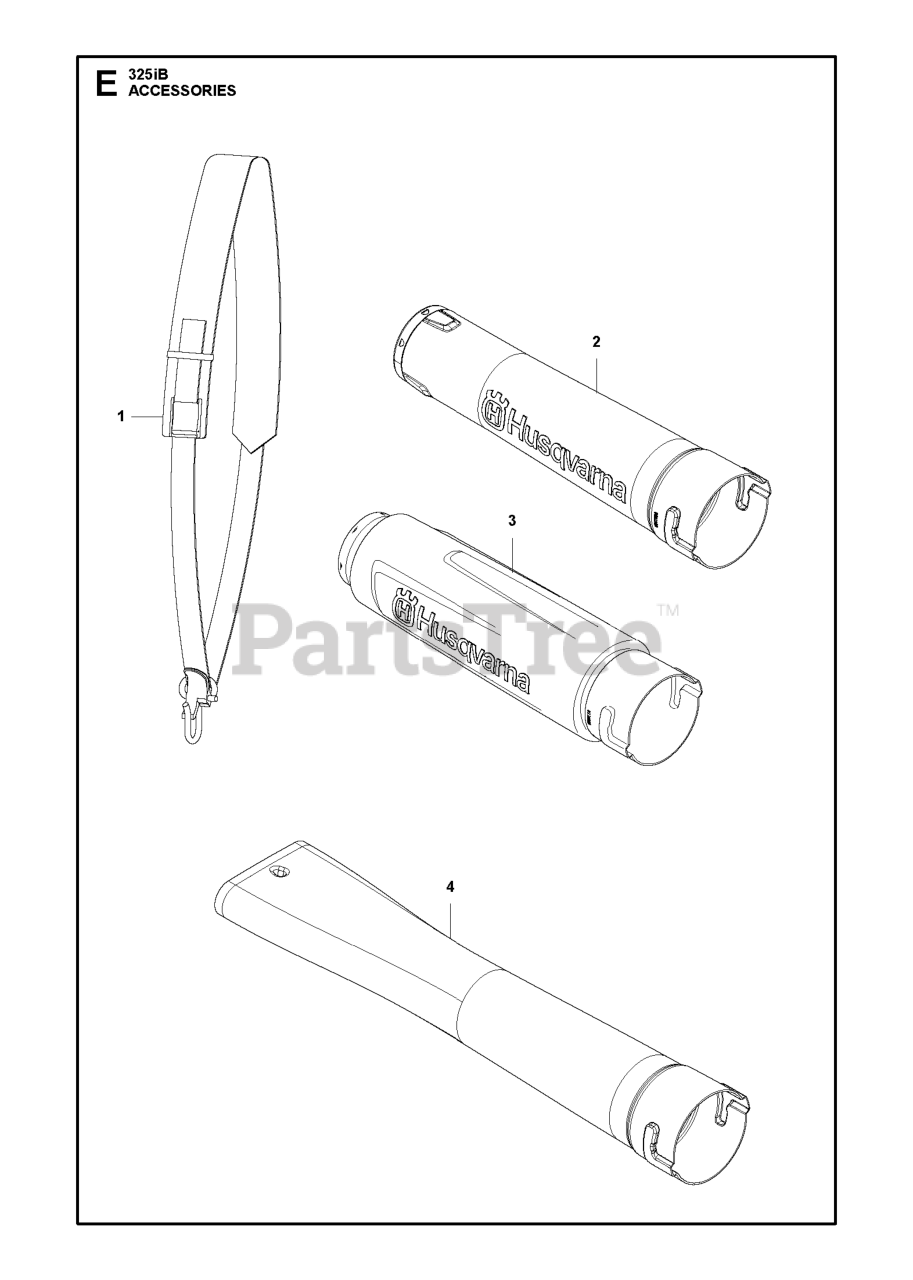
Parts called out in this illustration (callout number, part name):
1	Harness-w/o warning
2	TUBE ASSY NOZZLE 536LIBX
3	TUBE ASSY NOZZLE SILENCER
4	BLOWER NOZZLE FOR 320IB
